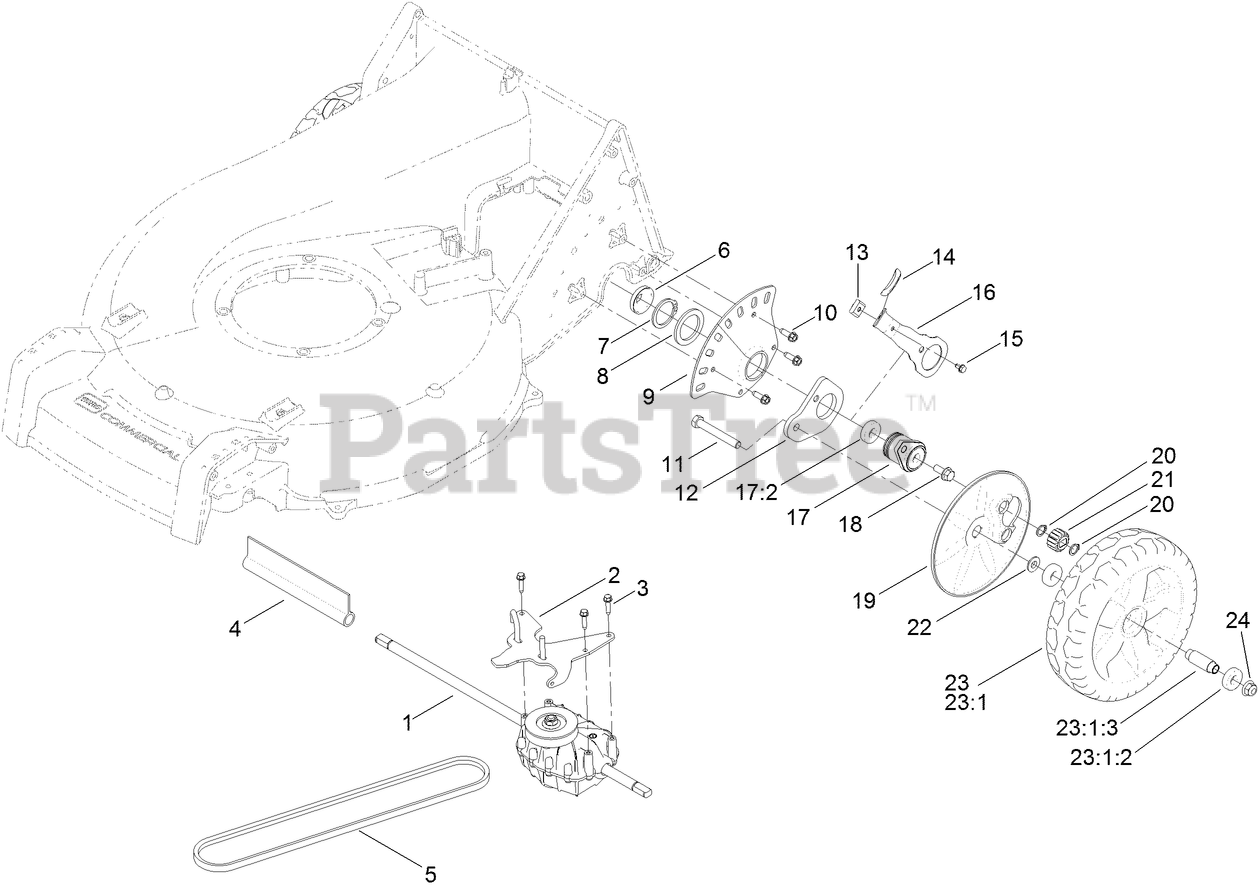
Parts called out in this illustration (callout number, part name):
1	TRANSMISSION
2	GUIDE-BELT
3	SCREW-SPECIAL
4	COVER-SHAFT, TRANSMISSION
5	BELT-V
6	COVER-BEARING
7	RING-RETAINING
8	Washer-Thrust
9	PLATE-HOC, REAR
10	SCREW-HWHTF
11	SCREW-HH
12	ARM-PIVOT, REAR
13	KEY-ARM, SPRING
14	KNOB-LEVER, HOC
15	SCREW-HWH
16	ARM-SPRING, REAR
17	BEARING RETAINER ASM
17:2	BEARING-BALL
18	SCREW-HWH
19	COVER-WHEEL
20	RING-RETAINING
21	GEAR-PINION, 15T
22	SPACER-COVER, WHEEL
23	WHEEL ASM
23:1	WHEEL
23:1:2	BEARING-BALL
23:1:3	SPACER
24	NUT-HF, NI
